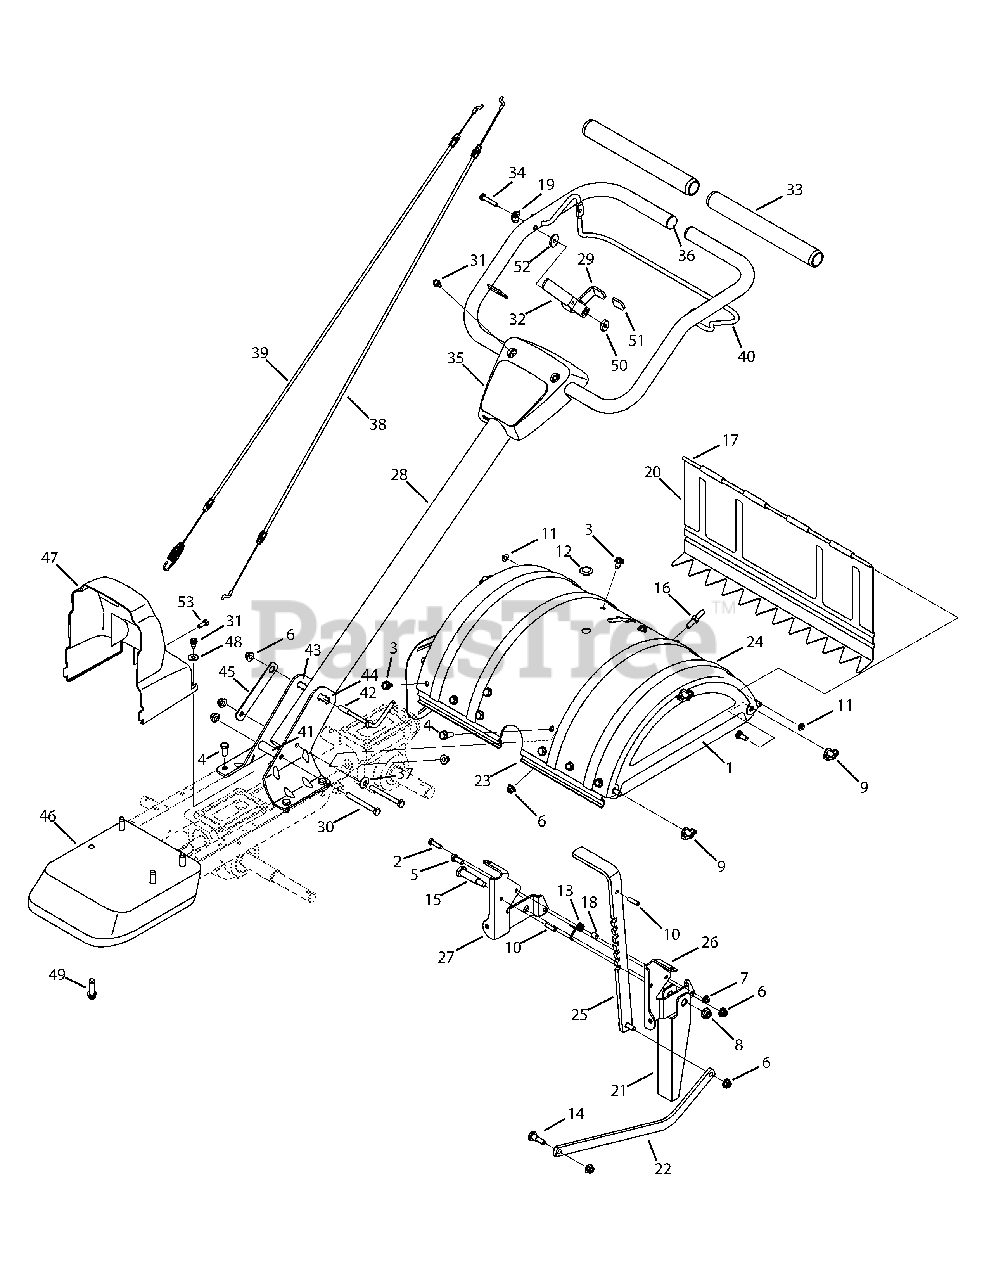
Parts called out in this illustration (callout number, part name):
1	End Cover Assembly
2	Hex Head Screw, 1/4-20 x 1
3	Hex Head Screw, 5/16-18 x .625
4	Hex Head Screw, 5/16-18 x .875
5	Hex Head Screw, 5/16-18 x .75
6	Hex Flange Top L-Nut, 5/16-18
7	Nylon Hex Lock Nut, 1/4-20
8	Flange Lock Nut, 3/8-16
9	Wing Nut, 5/16-18
10	Spirol Pin
11	Cap Nut, 1/4 Rod
12	Hole Plug
13	Torsion Spring
14	Shoulder Screw, .405 x .435 5/16-18
15	Shoulder Screw, .498 x 1.635
16	Stop Screw
17	Tiller Flap Rod
18	Spacer
19	Saddle Washer, .320 x .930 x .060
20	Rear Tine Shield
21	Reverse Stop Arm
23	Tine Shield Mounting Bracket
24	Tine Shield
25	Adjustable Depth Bar
26	Tail Bracket, LH
27	Tail Bracket, RH
28	Upper Handle Assembly
29	Reverse Handle Assembly
30	Hex Head Screw, 5/16-18 x 3.00
31	Self-Tapping Screw, 1/4-20 x 1/2
32	Handle Select
33	Foam Handle Grip
34	Hex Head Screw, 1/4-20 x 1.62
35	Handle Cover
36	Plug End
37	Bell Washer, .340 x .872 x .060
38	Reverse Cable
39	Forward Cable
40	Clutch Bail
41	Spacer, .322 x .625 x 2.00
42	Handle Crank
43	Handle Bracket, RH
44	Handle Bracket, LH
45	Retainer Nut Bracket
46	Front Bumper
47	Belt Cover
48	Flat Washer, .28 x .74 x .063
49	SEMS Screw, 3/8-16
50	Spacer, .375 x .165
51	Reverse Handle Grip
52	Flat Washer, .265 x .938 x .120
53	Self Tapping Screw, 1/4-14 x .625
